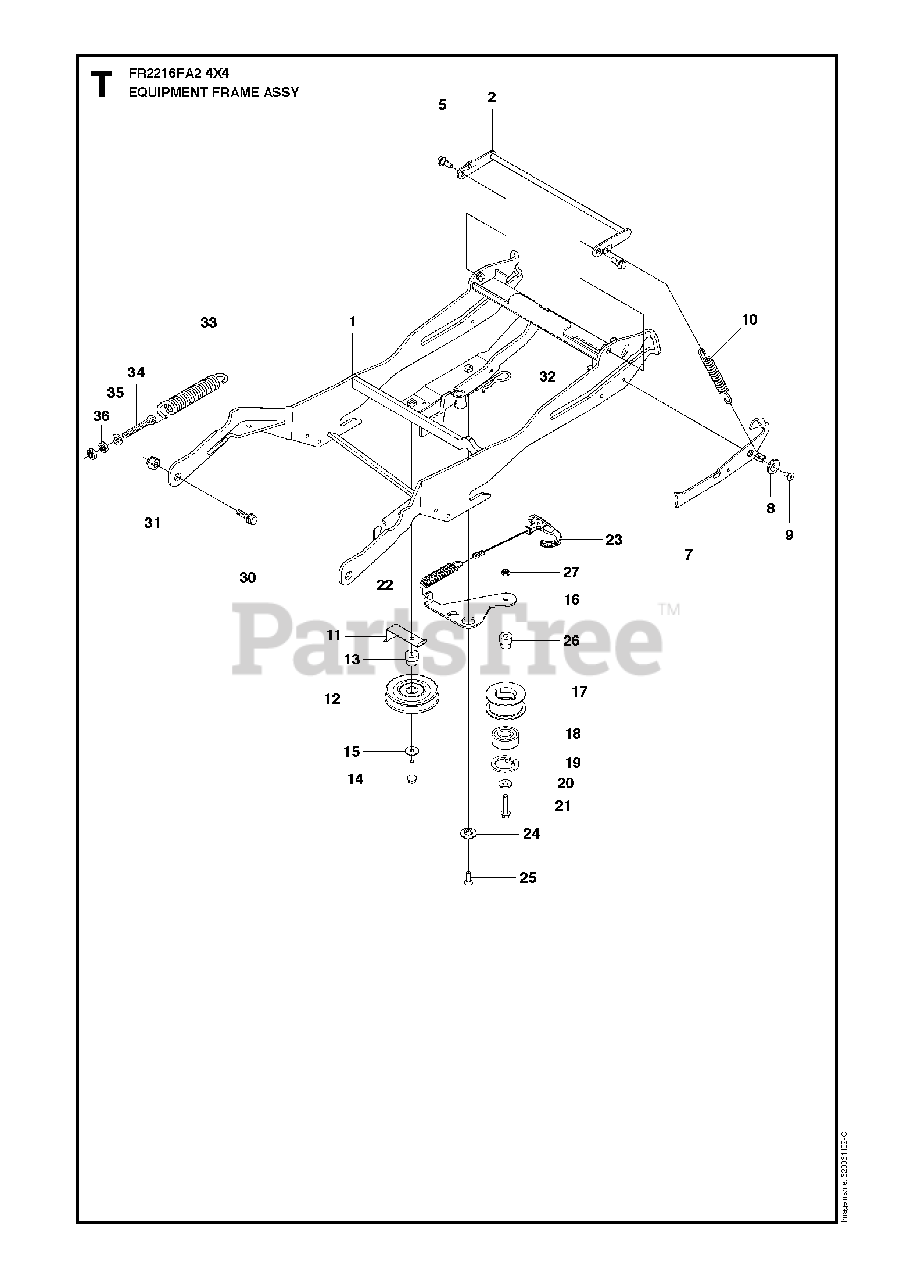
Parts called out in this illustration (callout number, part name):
8	SCREW IHCSFM
9	WHEEL ASSY
11	BELT GUIDE
17	%PULLEY
18	BALL BEARING 6004-2RS1
19	RETAINING RING
23	HANDLE ASSY
24	WASHER
27	LOCKNUT M8
35	WASHER
36	LOCKNUT M8
